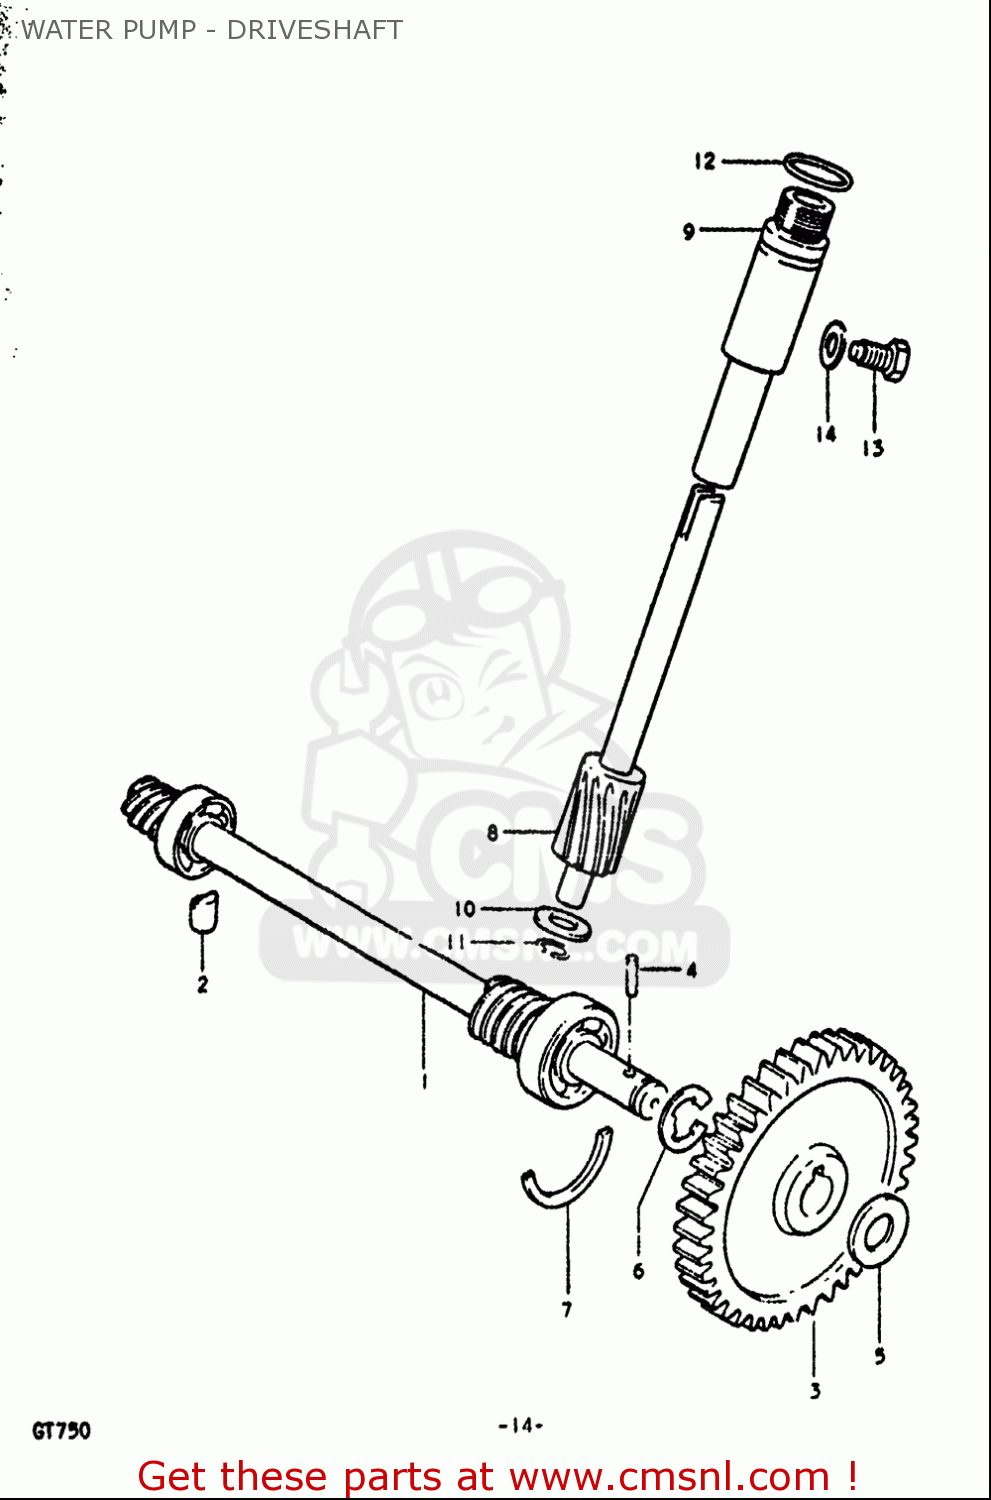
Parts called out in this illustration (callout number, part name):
4	PIN
5	SHIM(10X20X1)
6	E RING
10	SHIM(8X16X1)
11	CIRCLIP
12	O RING(D:1.7,ID:15.5)
13	BOLT
14	WASHER
